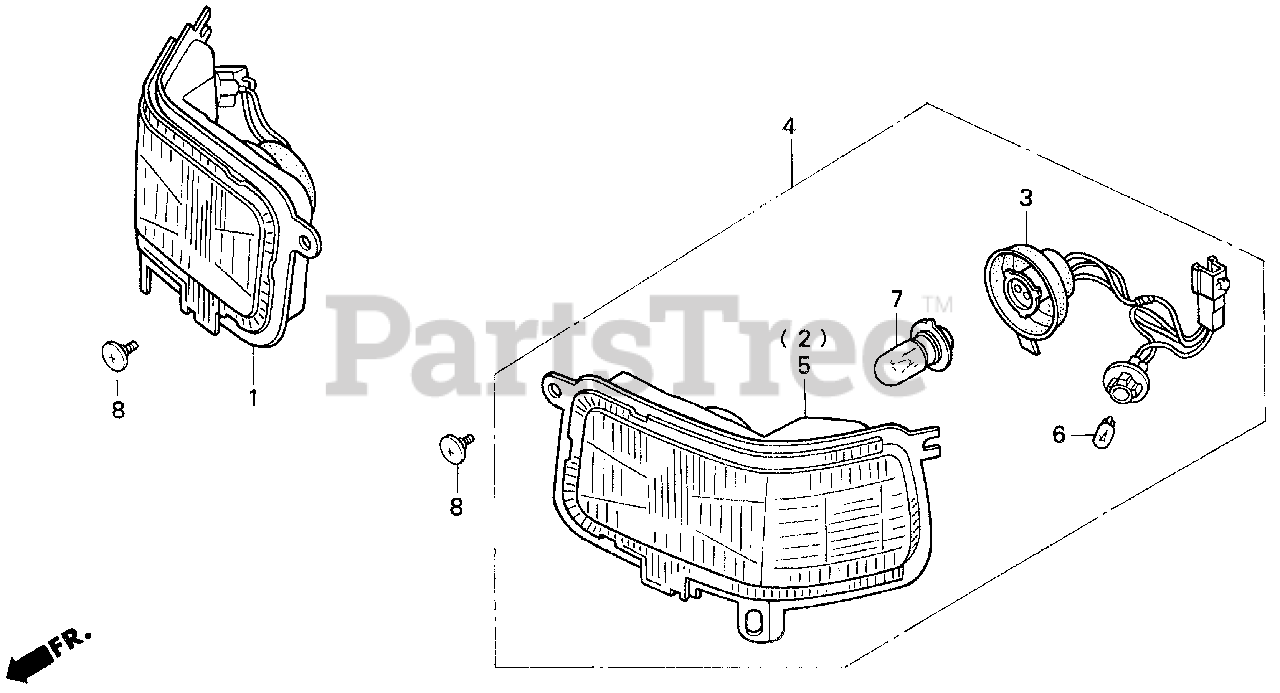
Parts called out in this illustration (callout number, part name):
1	HEADLIGHT ASSY., R. COMBINATION (STANLEY)
2	HEADLIGHT UNIT, R.
3	SOCKET, HEADLIGHT
4	HEADLIGHT ASSY., L. COMBINATION (STANLEY)
5	HEADLIGHT UNIT, L.
6	BULB (12V5W) (STANLEY)
7	BULB (12V25/25W) (STANLEY)
8	SCREW, METER VISOR SETTING
